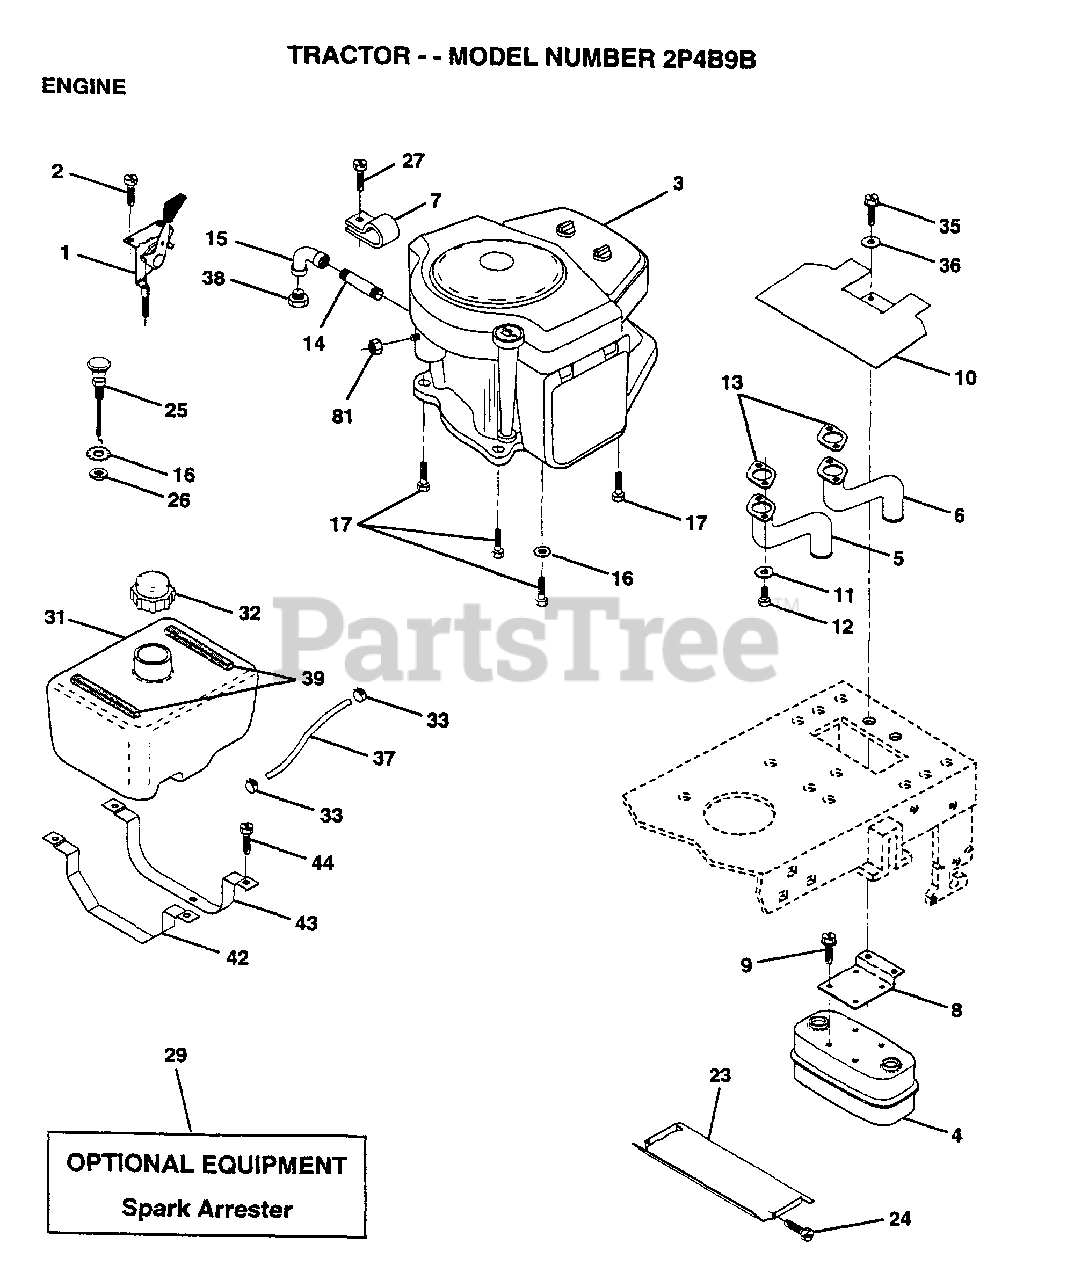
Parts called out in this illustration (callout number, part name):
2	SCREW LT
3	ENGINE B&S 18HP
5	EXHAUST.B&S.18.LH
6	EXHAUST.B&S.18.RH
7	CLAMP.TUBE.DBL.EN
8	BRACKET MUFFLER
9	SCREW ST
10	SHIELD.HEAT.
14	PIPE NIPPLE LT
15	ELBOW
16	LOCKWASHER
17	SCREW LT
23	HEAT SHIELD
24	SCREW
25	CONTROL.CHOKE.37
27	SCREW.10-24X1/2
31	TANK FUEL 1.9 NAT
32	CAP ASM FUEL
33	HOSE CLAMP
35	SCREW
36	WASHER
37	FUEL LINE T
42	STRAP TANK FUEL
43	STRAP TANK FRONT
44	SCREW
81	NUT
